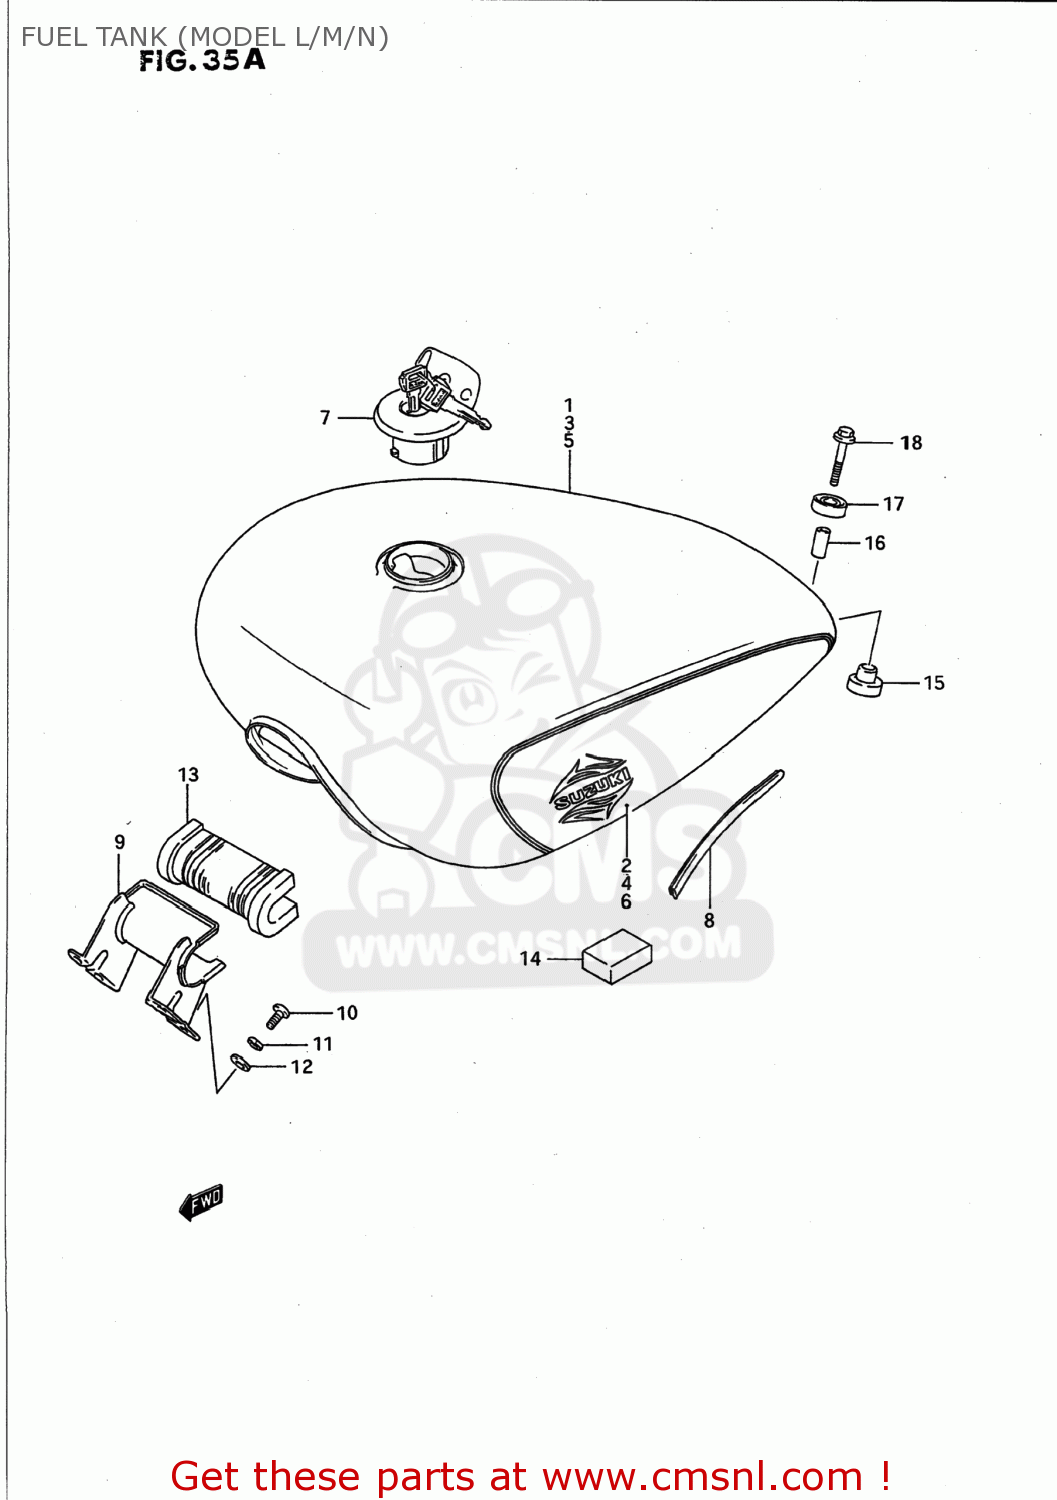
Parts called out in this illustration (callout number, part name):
1	TANK ASSEMBLY,FUEL
2	TAPE SET,FUEL TANK
3	TANK ASSEMBLY,FUEL
4	TAPE SET,FUEL TANK
5	TANK ASSEMBLY,FUEL
6	TAPE SET,FUEL TANK
7	CAP SET,FUEL TANK
8	MOLDING,FUEL TANK
9	BRACKET COMP,FUEL TANK
10	SCREW
11	WASHER,LOCK
12	WASHER
13	CUSHION,FUEL TANK FR
14	CUSHION
15	CUSHION
16	SPACER
17	CUSHION
18	BOLT
